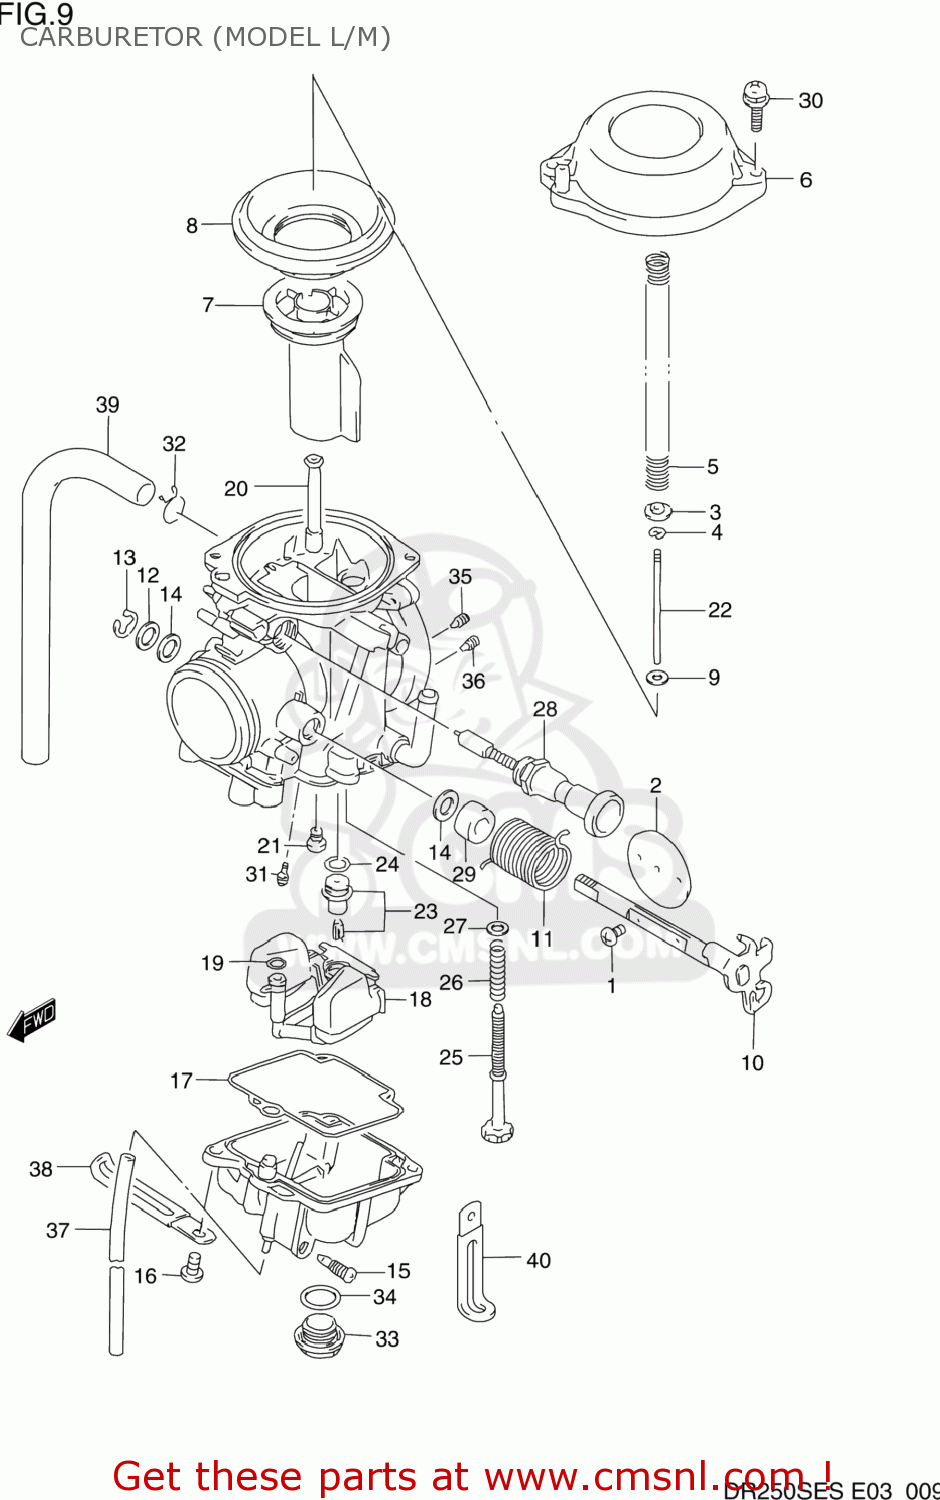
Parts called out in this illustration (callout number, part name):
1	SCREW
2	VALVE,THROTTLE (115)
3	RING
4	E RING
5	SPRING
6	COVER,DIAPHRAGM
7	VALVE PISTON
8	DIAPHRAGM
9	RING
10	SHAFT ASSEMBLY
11	SPRING
12	GASKET,THROTTLE SHAFT (NAS)
13	E RING
14	SEAL
15	PLUG,DRAIN
16	SCREW
17	GASKET,FLOAT CHAMBER (NAS)
18	FLOAT ASSY
19	O RING
20	JET,NEEDLE (O-6)
21	JET,MAIN(130)
22	NEEDLE,JET
23	VALVE ASSEMBLY,NEEDLE
24	O-RING,NEEDLE VALVE
25	SCREW,ADJUSTER
26	SPRING
27	WASHER
28	PLUNGER ASSY
29	RING
30	SCREW
31	JET(40)
32	CLIP
33	SCREW,GUIDE
34	O RING,DRAIN PLUG
35	JET,PILOT AIR,1.4
36	JET,AIR(0.6)
37	HOSE
38	CLIP
39	HOSE
40	CLAMP L:35
